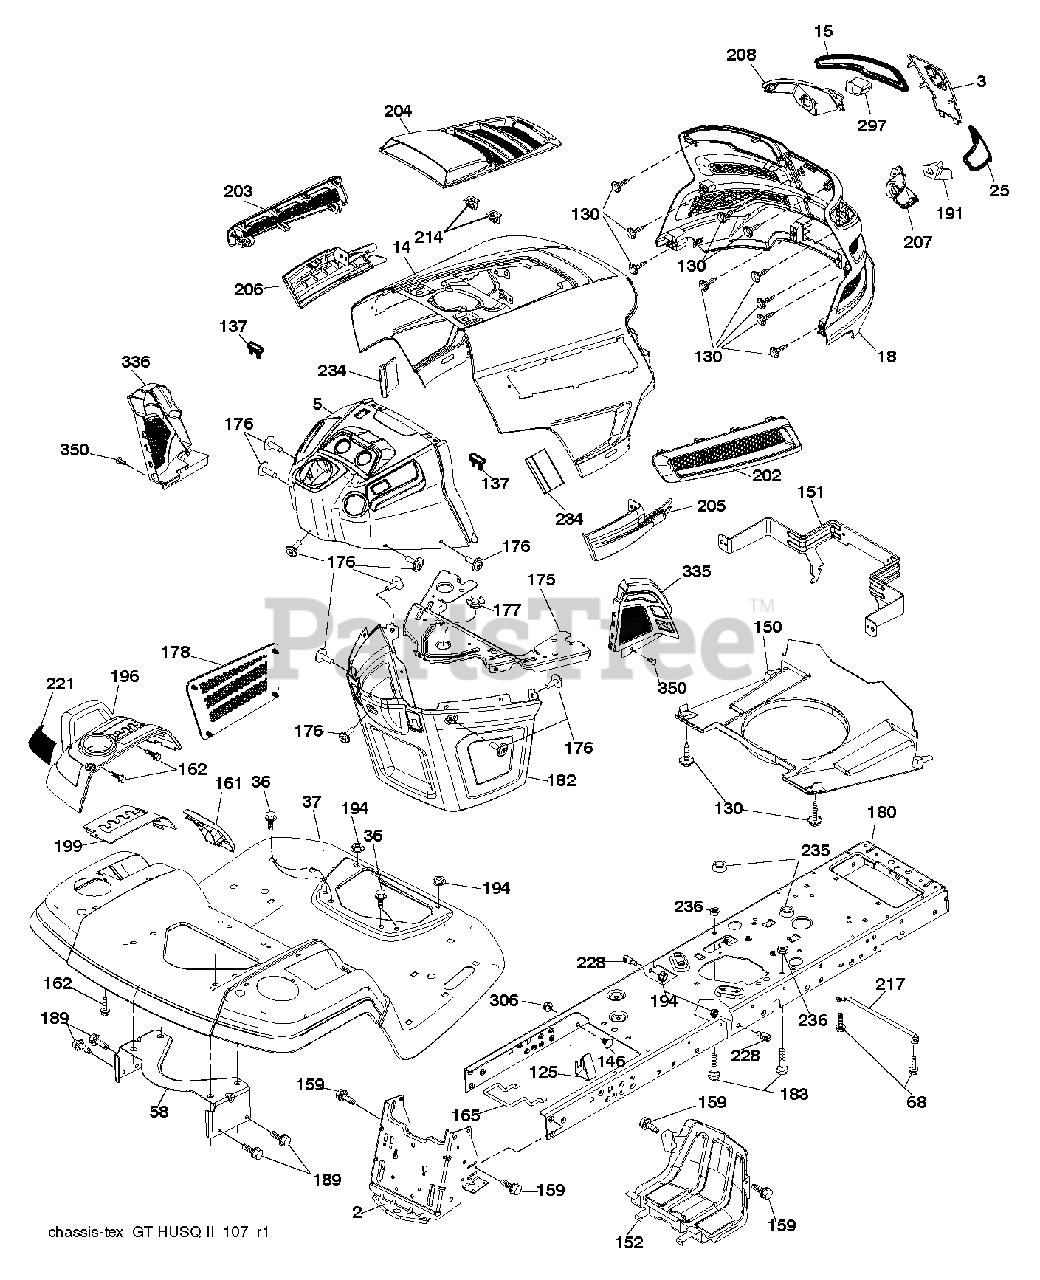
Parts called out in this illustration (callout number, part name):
2	DRAWBAR.STGT
3	APPLIQUE.SUBASM.GT.HUSQ.II
5	DASH.UPP.GT2.DR.PTO.DCKLFT.MC
14	HOOD.ASM.HUSQVARNA.GT.TEX.422
15	LENS.HEADLIGHT.LH.GTII.2011
18	GRILLE.SUBSTRATE.2011.
25	LENS.HEADLIGHT.RH.GTII.2011
36	SCREW 5/16"
37	FENDER.PNT.TX.GT.CH/FW/DL.HUSQ
58	BRKT.SUPPORT.FNDR/TANK
68	SCREW LT
125	CLIP.FUEL.LINE
130	SCREW.#10 X 0.750.BOS
137	BUMPER DASH
146	BOLT.RDHD.SHT.SQNK.3/8-16X5/8
150	AIR.DUCT.GTV.BLACK
151	BRACKET.PIVOT.HOOD.GT.HUSQ.II
152	SHIELD.BROWNING.PNT.GT.V2
159	SCREW, 3/8-16X3/4
161	CONSOLE.WINDOW.FUEL.HUSQ.GT
162	SCREW.HI-LO.CONSOLE
165	SUPPORT.TANK.REAR.B/TE
175	PLATE.CROSSMEMBER.HUSQ
176	SCREW.#10-24X5/8.RN.QU
177	BUSHING, STEERING
178	CARGO.ASM.NET.TXGT.W/C
180	CHASSIS.TEX.BOLTED
182	DASH.LOWER.COMMON.12V.ADAPTOR
183	BOLT.5/16-18X1-1/4 FULL THD
189	SCREW
191	INSERT.REFLECTIVE.RH.HUSQ.GTII
194	NUT LOCK HEX FLANGE 5/16-18
196	CONSOLE.ASM.DECKLIFT.HUSQGT.DL
199	PLATE.DECK.LIFT.HUSQVARNA.GT
202	VENT.SIDE.RH.GT.HUSQ.II.
203	VENT.SIDE.LH.GT.HUSQ.II.498
204	VENT.TOP.HUSQ.GT2
205	SIDE.TRIM.RH.GT.HUSQ.II
206	SIDE.TRIM.LH.GT.HUSQ.II.GRAY
207	BEZEL LIGHT.RH.GT.II.MYLAR
208	BEZEL LIGHT.LH.GT.II.MYLAR
214	CLIP.RETAINER.TINNER.
217	ROD.PIVOT.HOOD
221	REFLECTOR.LH.TEX GT HU
228	STUD.FASTNER.W/ANTI-ROTATE
234	BUMPER.HOOD.TEX.HUSQVARNA
235	SPACER FENDER
236	NUT.CENTERLOCK.5/16-
297	INSERT.REFLECTIVE.LH.HUSQ.GTII
306	NUT LOCK FLG 3/8-16 UNC
335	COVER.LOWER.DASH.RH.BLACK
336	COVER-LH.LOWER.DASH.GT2.BLACK
350	KIT GUARD BRUSH
